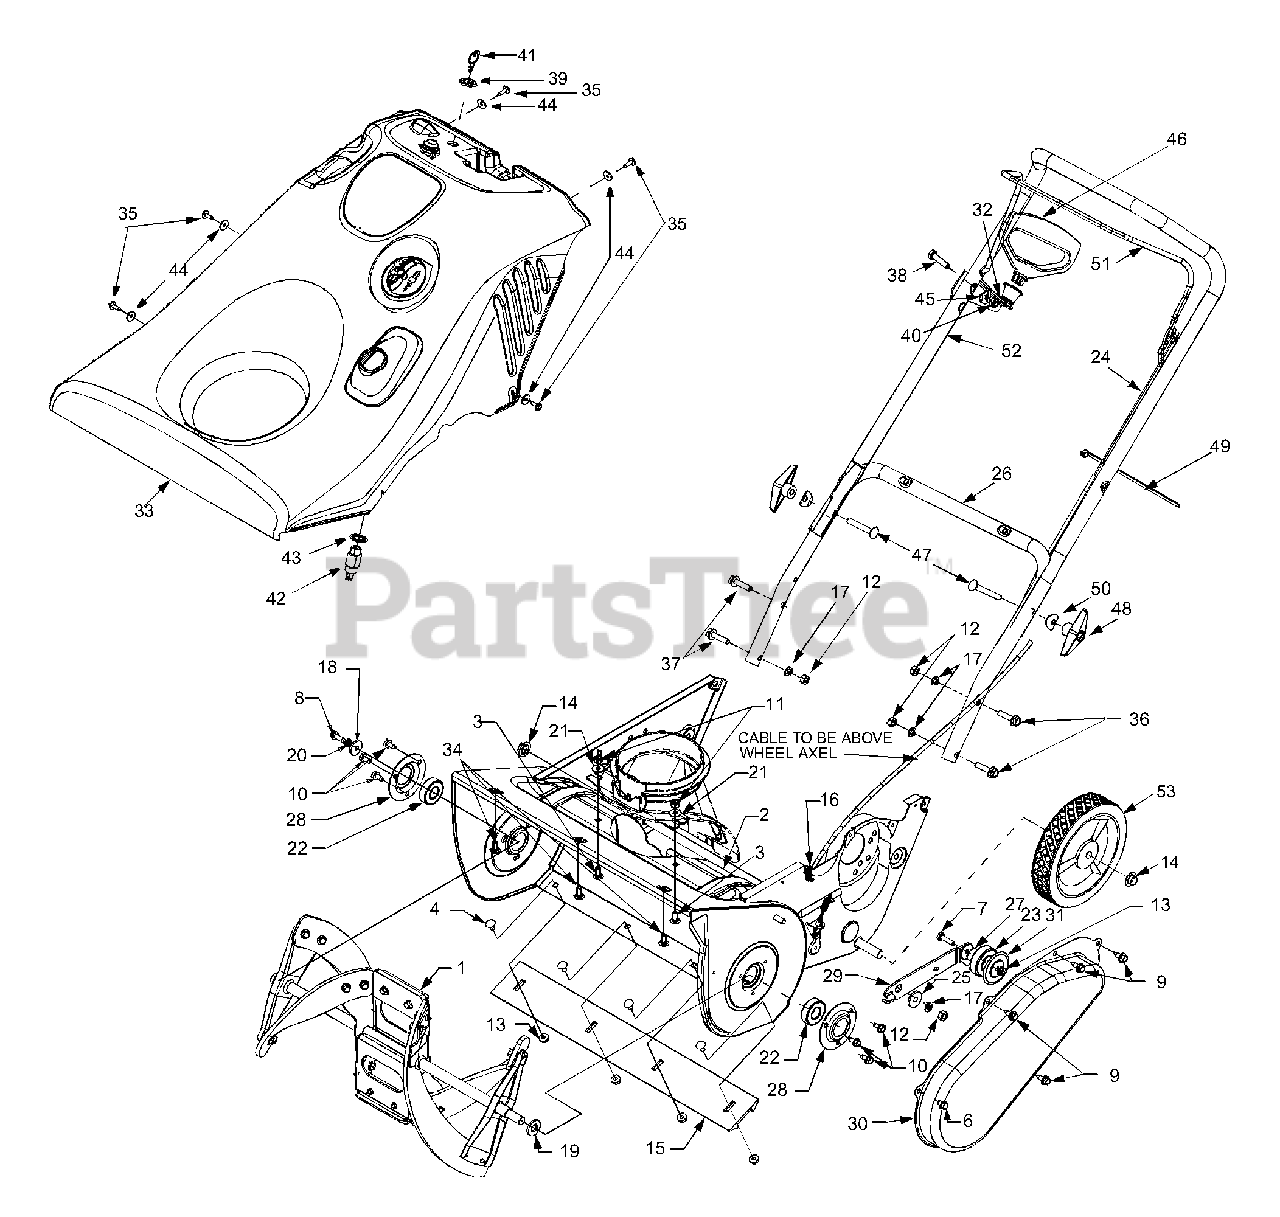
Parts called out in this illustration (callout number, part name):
1	Auger Ass'y 21" complete w/Solid Shaft
4	Carriage Bolt 1/2-20 x .50 LG
5	Truss Mach Scr 5/16-18 x .75
6	Hex "B" Tap Scr. 1/4-14 x .375" LG
7	Hex Screw 1/4-20 x 1.00 Gr. 5
8	Hex Tap Scr. 1/4-20 x .75"
9	Hex Screw AB:1/4-14 x 0.625"
10	Hex Tap Scr. 1/4-14 x .50" LG.
11	Hex Nut, 1/4-20 Nylon
12	Hex Nut 5/16-18 hd. Gr. 5
13	Hex Flange Nut, 1/4-20
14	Push Cap x 1/2" Rod
15	Shave Plate 2.66 x 19.88 Double
16	Extension Spring .33 OD x 1.12 Lg.
17	L-Wash 5/16 ID
18	Flat Washer .265 ID x .938 OD x .120
19	Flat Washer .510 ID x 1.00 OD x .125
20	Lock Washer, 1/4
21	Flat Washer .260 x .720 x .060
22	Ball Bearing 17 x 40 x 12
23	Ball Bearing
24	Control Cable
25	Shoulder Spacer .25 THK
27	Flange Spacer
31	Belt Keeper
32	Mitten Grip Bracket
33	Shroud Ass'y, 7HP Yellow
34	Screw, 1/4-15 x .75
35	Hex Wash B-Tapp Scr #10-16 x .625" Lg.
36	Hex Flange Screw, 5/16-18x 1.25
37	Hex Flange Screw 5/16-18 x 1.50 Gr. 5
38	Hex Screw, 5/16-18 x 1.375
39	Hex Nut 5/8-32 x .12 Special
40	Hex Nut, 5/16-18 Gr 5 Nylon
41	Ignition Key
42	Key Switch-Electric Start
43	L-Washer Internal .625 ID x 1.058 OD
44	Flat Washer .194" ID x .62" OD x .063
45	Saddle Washer .320 ID x .93 OD
46	Recoil Handle, Mitten
47	Carriage Bolt 5/16-18 x 2.0 Gr. 1
48	Handle Knob Assembly 5/16-18
49	Hex Screw 5/16-24 x .75 Gr. 5
50	Carriage Bolt, 5/16-18 x.075 GR 1
53	Wheel, 7 x 1.5 Star Yellow
